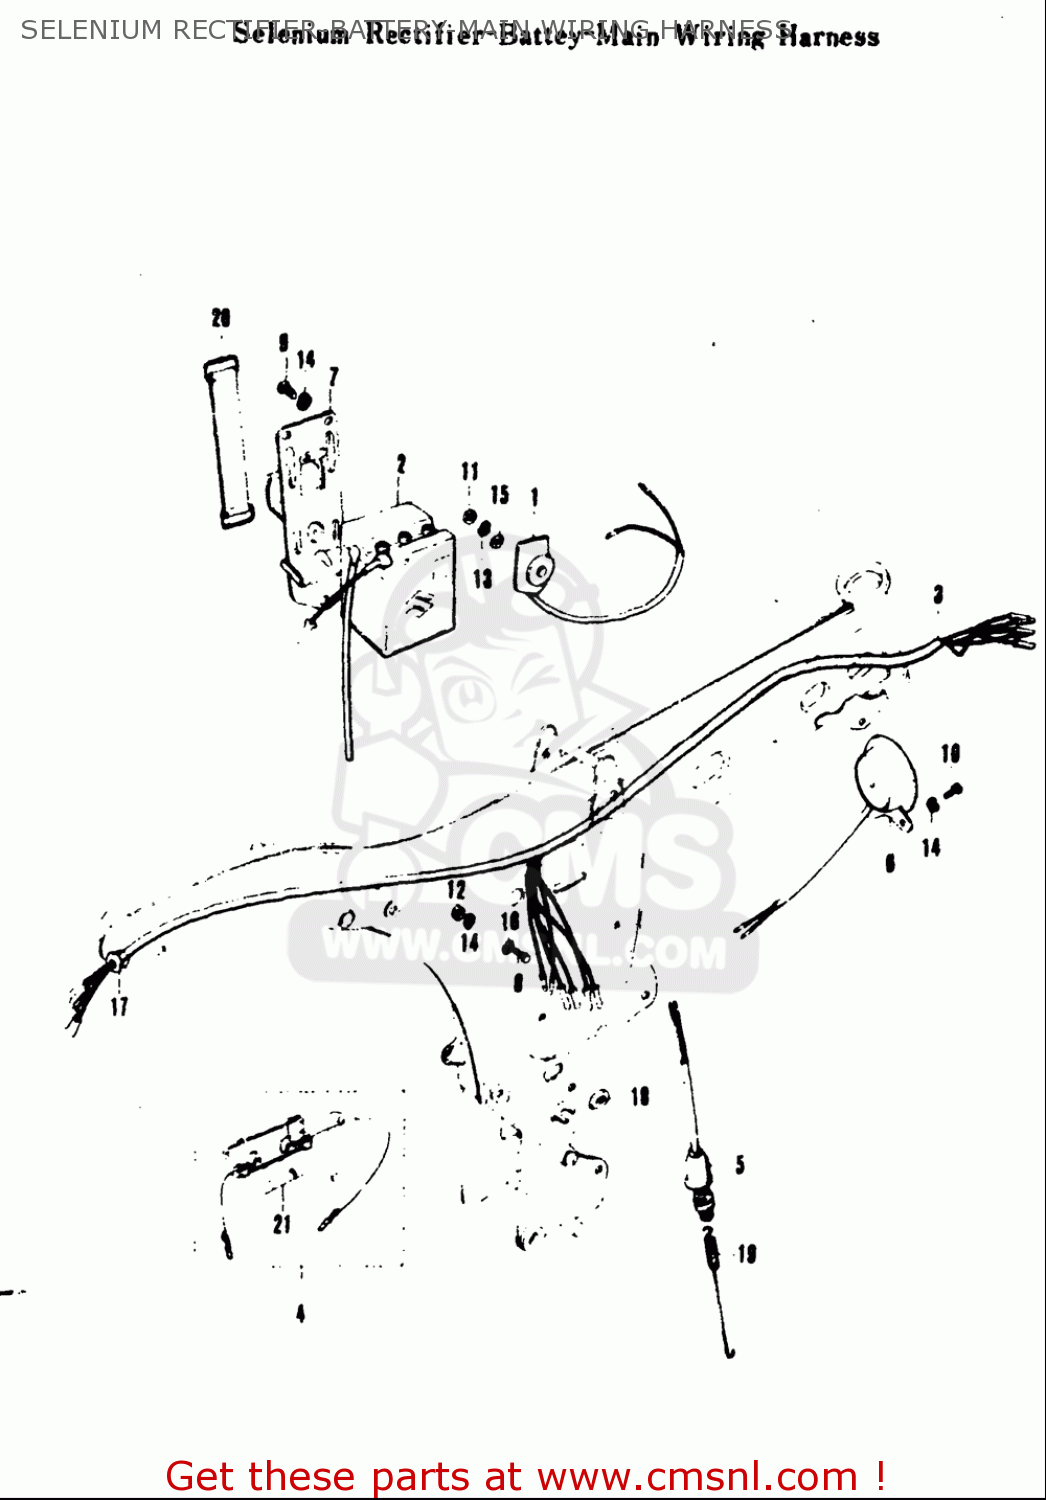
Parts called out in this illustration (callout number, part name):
1	RECTIFIER ASSY
2	BATTERY ASSY(6N4-2A4.2AH)
4	CASE ASSY,FUSE
10	SCREW
11	NUT
12	NUT
13	WASHER,LOCK
14	WASHER,LOCK
15	WASHER
16	WASHER
20	BAND
